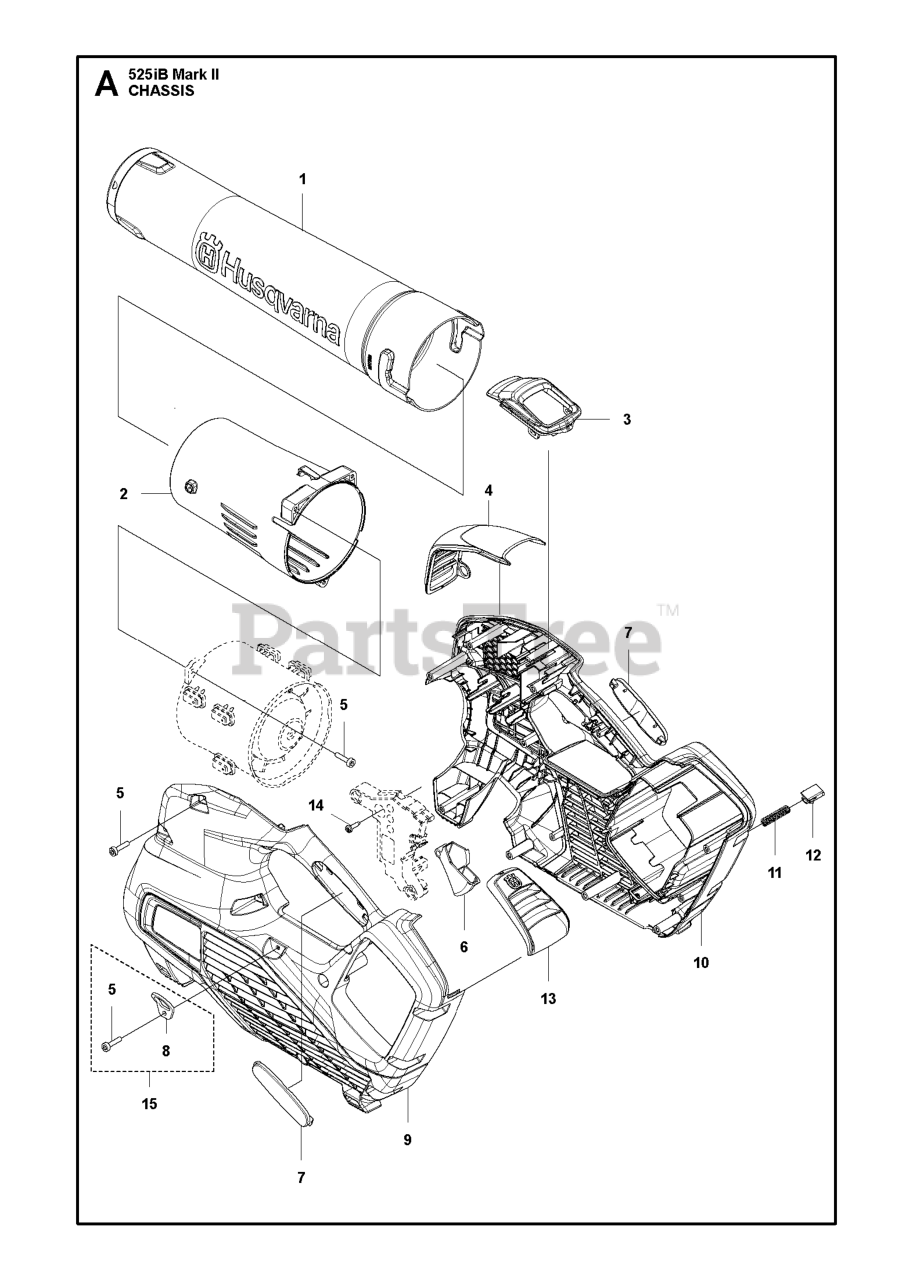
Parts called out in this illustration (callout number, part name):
1	TUBE ASSY NOZZLE 536LIBX
2	TUBE FAN SYSTEM
3	KEYPAD FRAME
4	FRONT COVER
5	SCREW ITXSCT PW4.2X18 10.9 ZN
6	THROTTLE CONTROL
7	HANDLE INSERT GREY
9	HOUSING LEFT
10	HOUSING RIGHT
11	SPRING PUSH OUT
12	PUSH BUTTON
14	SCREW CITXPANT
15	KIT EYELET
